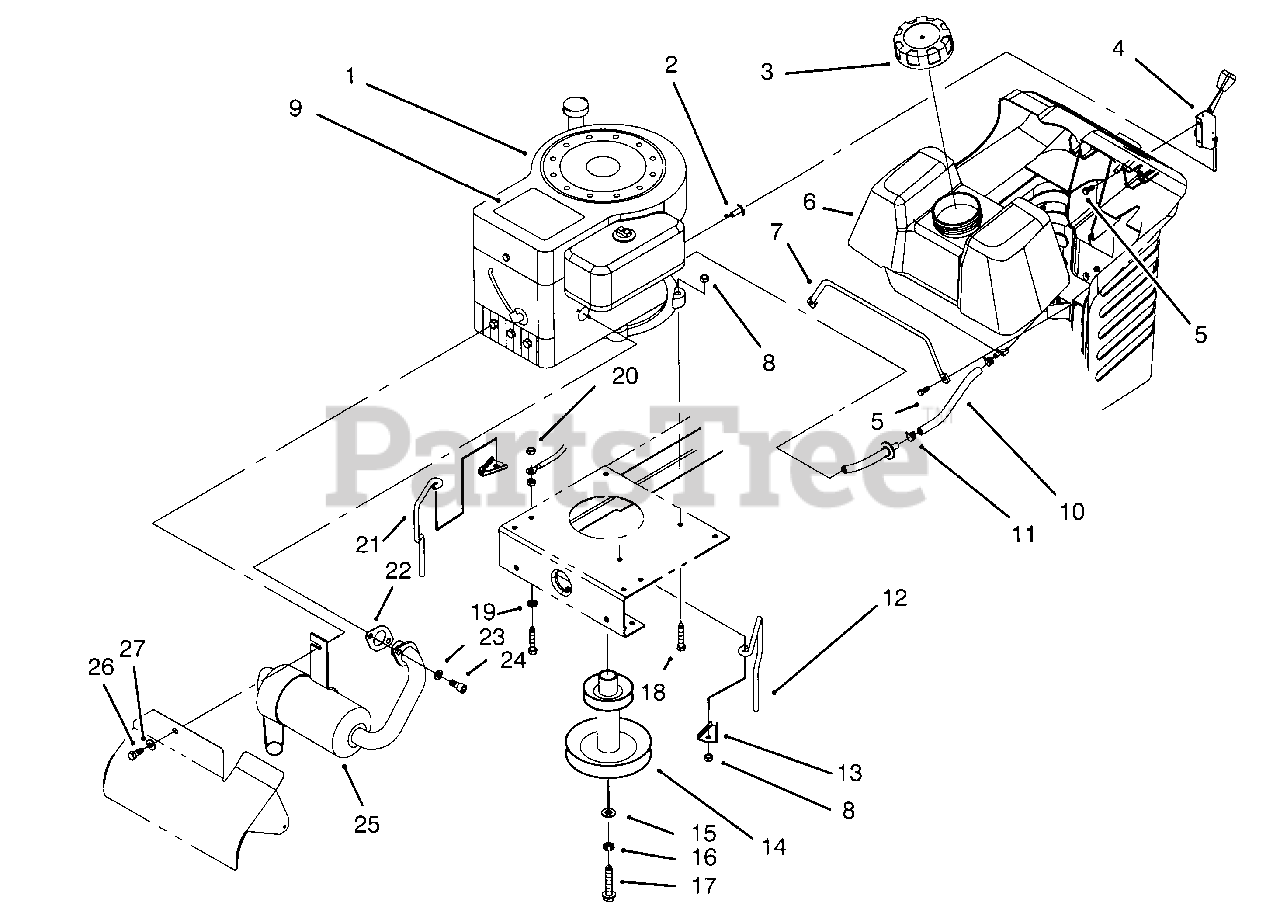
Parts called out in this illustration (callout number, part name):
1	Engine-12.5 H.P.(Model No. 81180 Only)
2	Cable-Throttle
4	Control-Throttle
5	Screw-Plastite
6	Tank-Gas
7	Rod-Gas Tank
8	Nut-Lock
9	Decal-Engine 12.5(Model No. 81180 Only)
10	Line-Fuel
11	Clamp-Hose
12	Guide-Belt L.H.
13	Anchor-Belt Guide
14	Pulley-Engine
15	Washer-Flat
16	Washer-Lock
17	Bolt-Blade
18	Screw-Hex Hd. Cap
19	Washer-Ext. Tooth Lock
20	Nut-Keps
21	Guide-Belt R.H.
22	Gasket-Muffler
23	Washer-Lock
24	Screw-Hex Soc. Hd.
26	Screw-Hex Hd. Cap
27	Washer-Lock
